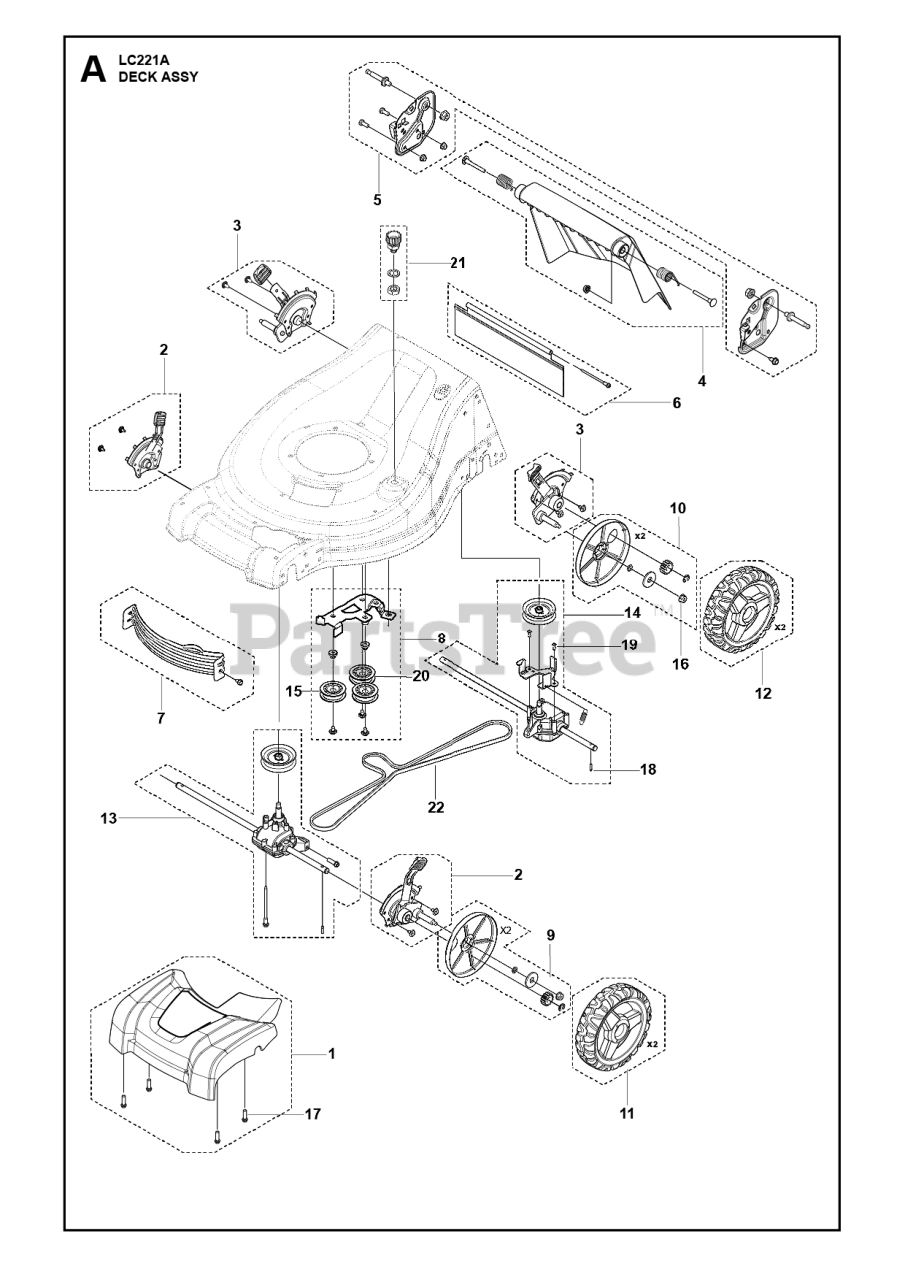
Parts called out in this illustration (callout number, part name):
1	Covers
2	Wheels
3	Wheels
4	Doors
5	Handles
6	Guards
7	Baffles
8	Pulleys
9	Wheels
10	Wheels
11	Wheels
12	Wheels
15	PULLEY.ASM.22+ AWD
16	NUT.HEX.FLANGE.3/8-16.LO(3 2)
17	SCREW.HI-LO. 5/16 X 1.00
18	PAWL, DRIVE
19	SCREW
20	PULLEY.RWD.IDLER.DBL SEAL
21	KIT.WASH-OUT.PORT
22	BELT.DRIVE.21EFF.AWD
